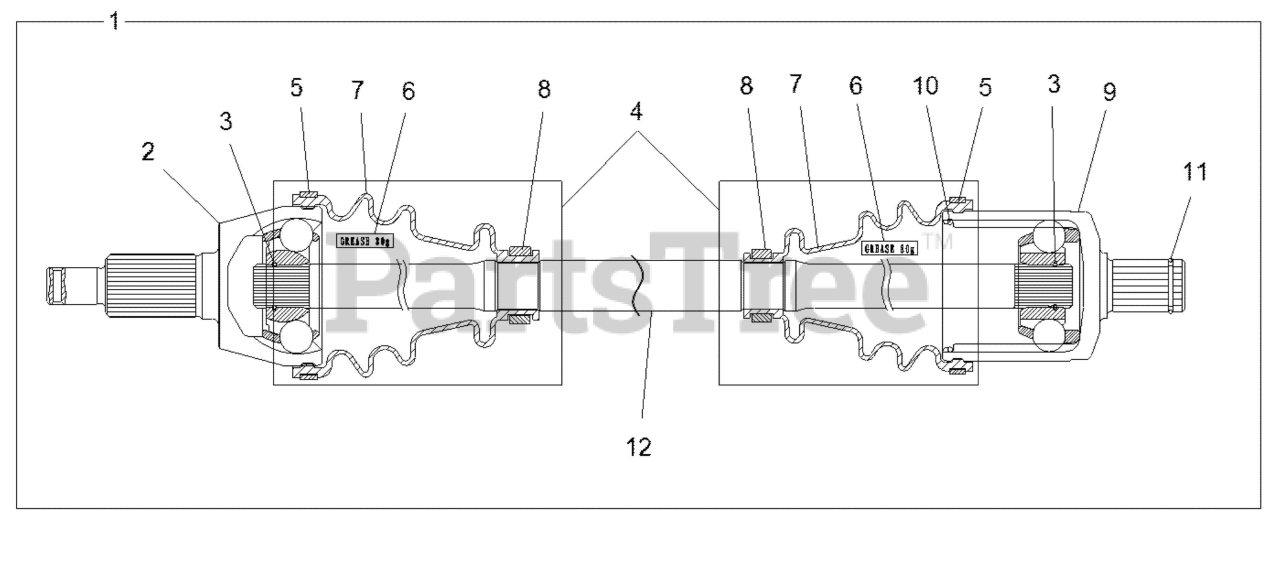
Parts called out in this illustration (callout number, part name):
1	ASM-HALF SHAFT,FRONT,LT
2	JOINT-CV,OUTER
3	CIRCLIP-1.8X22.2(PR-3011)
4	KIT-BOOT,PLUNGING JNT(PR-8062)
5	CLAMP-LARGE(PR-2019)
6	GREASE(K575/VW738)
7	BOOT(PR-0015)
8	CLAMP-SMALL(PR-0016)
9	JOINT-CV,INNER
10	CIRCLIP-2.0X61.7(PR-2016)
11	CIRCLIP-1.6X24.4(PR-2025)
12	SHAFT,23.5(PR-315)
